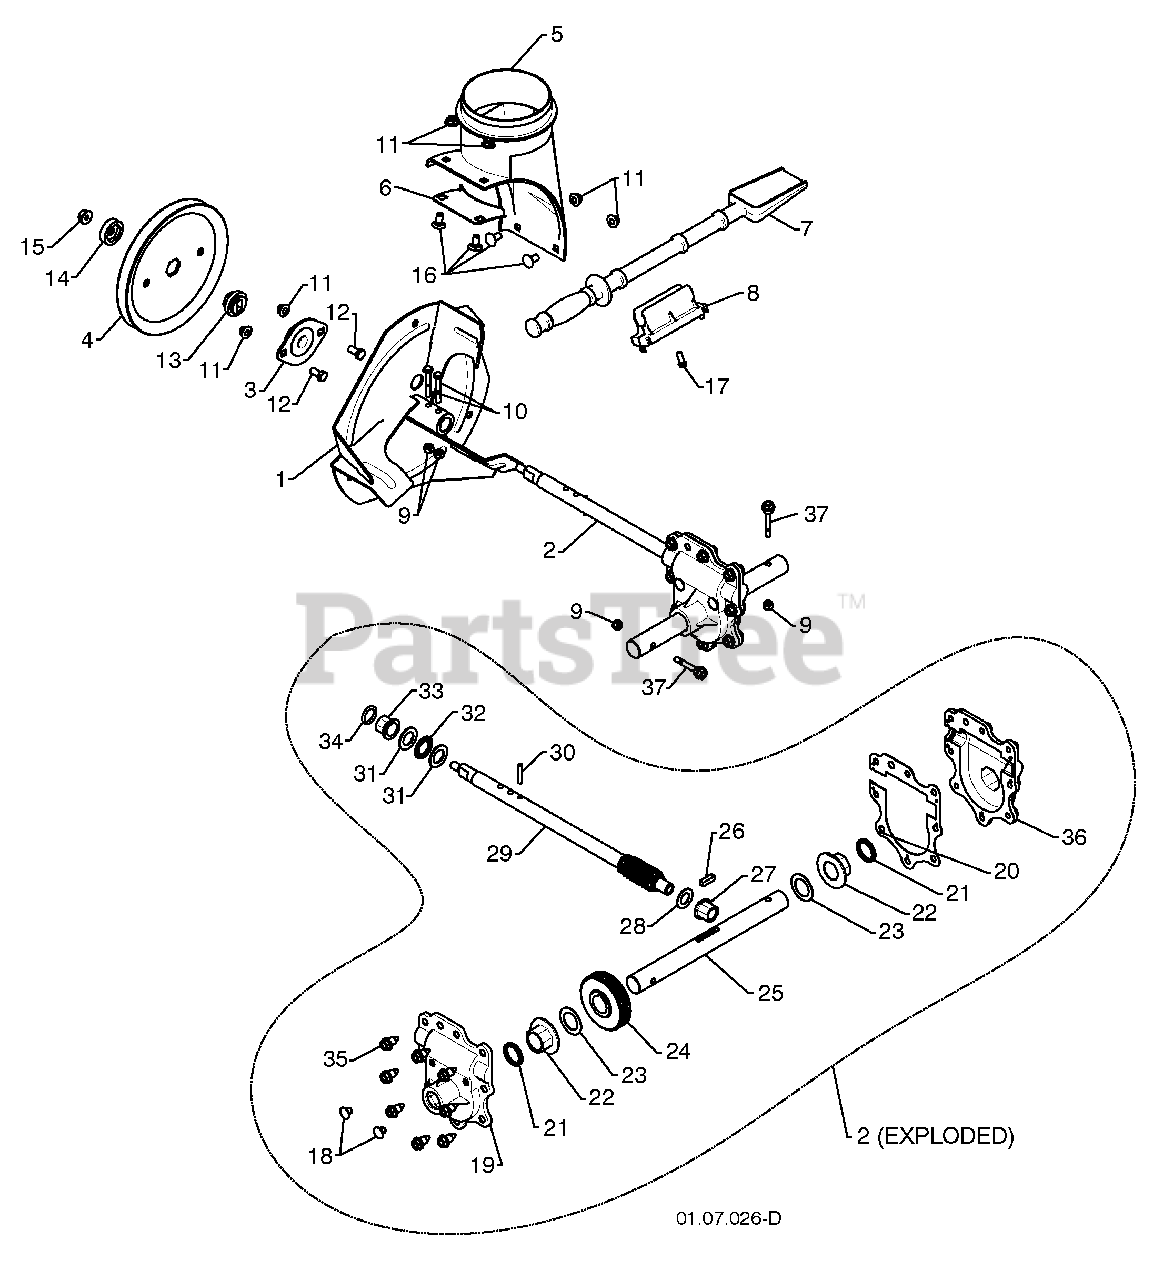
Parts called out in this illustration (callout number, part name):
1	IMPELLER
2	GEARBOX ASSEMBLY
3	BEARING
4	IMPELLER PULLEY
5	DISCHARGE BASE
6	CORNER BRACKET
7	CLEAN OUT TOOL
8	TOOL CLIP
9	NUT 1/4-20
10	SCREW 1/4-20 X .625
11	NUT 5/16-18
12	SCREW 5/16-18 X .625
13	IMPELLER HUB
14	IMPELLER SLEEVE
15	NUT 3/8-16
16	CARRIAGE BOLT
17	SCREW 13-16 X .625
19	GEARBOX COVER RH
20	GASKET
22	BEARING
23	THRUST WASHER 1.00
25	AUGER SHAFT
26	SQUARE KEY
28	THRUST WASHER
29	IMPELLER SHAFT
31	THRUST WASHER
32	THRUST BEARING
34	O-RING
35	SCREW 5/16-18 X .750
36	GEARBOX COVER LH
37	SHEAR BOLT
